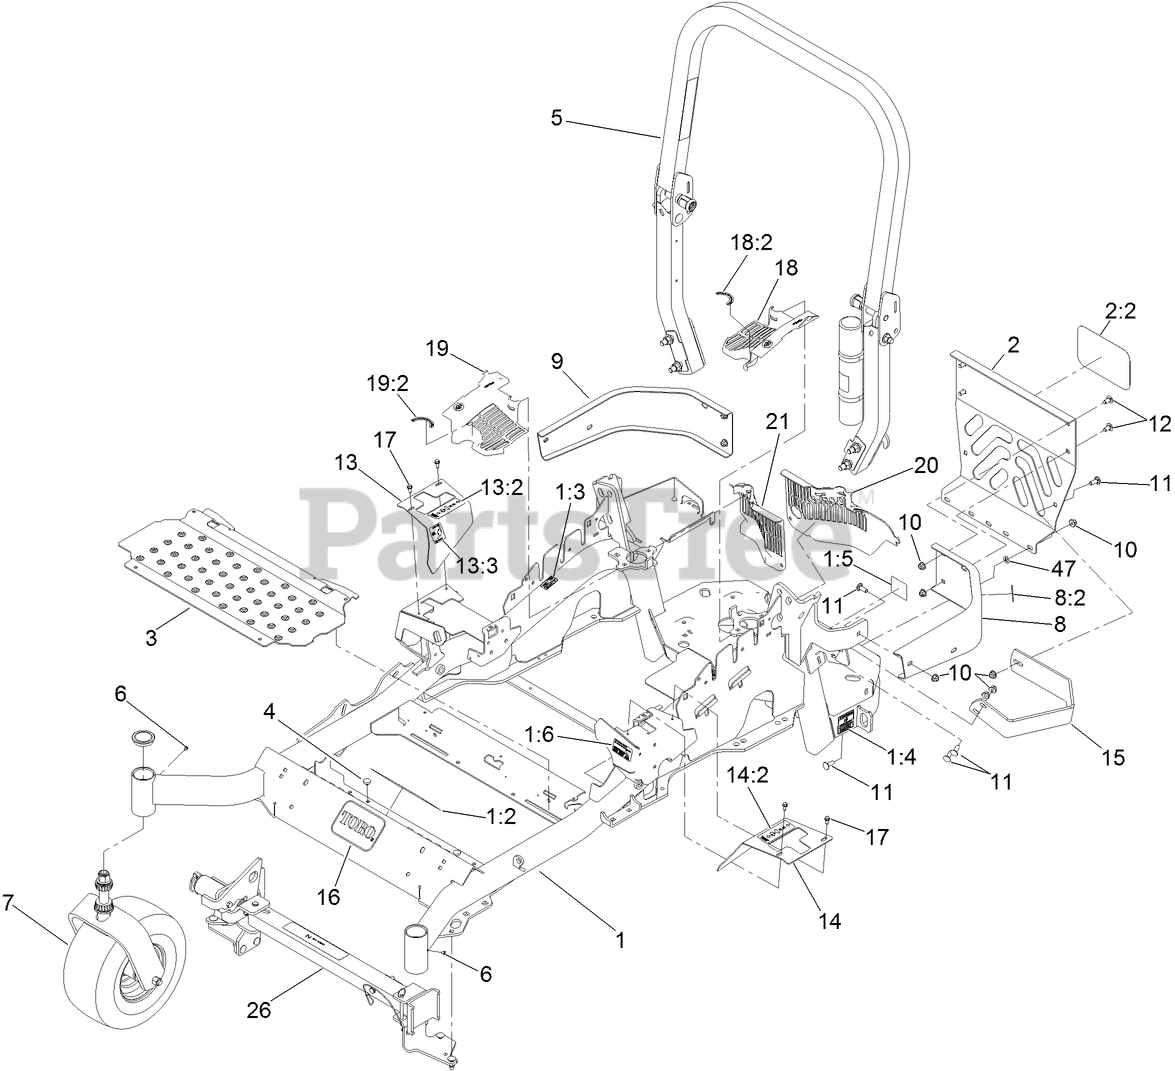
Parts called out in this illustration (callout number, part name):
1	MAINFRAME ASM
1:2	DECAL-SLOPE
1:3	DECAL-CAUTION
1:4	DECAL-BELT DRIVE
1:5	DECAL-SPARK ARRESTER
1:6	DECAL-FUEL FILL
2	REAR GUARD ASM
2:2	DECAL
3	FLOORPAN
4	BUMPER
5	ROPS ASM
7	FRONT CASTER ASM
8	BUMPER-REAR, LH
8:2	DECAL-CAUTION
9	BUMPER-RH
10	NUT-HF, NI
11	SCREW-CARR
12	SCREW-CARR
13	RH MOTION CONTROL COVER ASM
13:2	DECAL-MOTION CONTROL
13:3	DECAL-PARK BRAKE
14	LH MOTION CONTROL COVER ASM
14:2	DECAL-MOTION CONTROL
15	GUARD-MUFFLER
16	DECAL
17	SCREW-HWH
18	LH HYDRO GUARD ASM
18:2	DECAL-HYDRO OIL
19	RH HYDRO GUARD ASM
19:2	DECAL-HYDRO OIL
20	GUARD-HYDRO, REAR (LH)
21	GUARD-HYDRO, REAR (RH)
26	Z STAND ASM
47	NUT-PUSH
